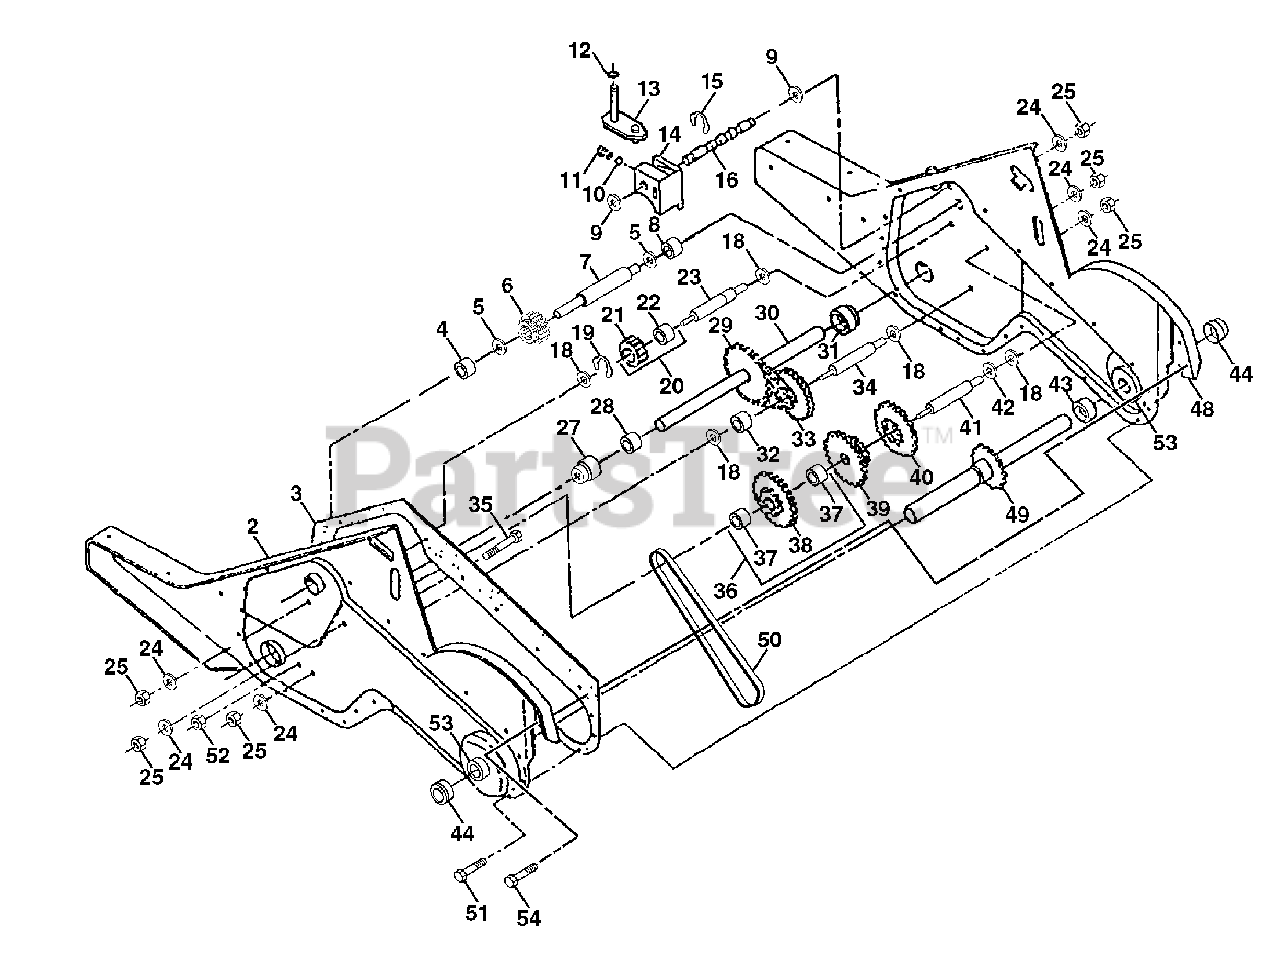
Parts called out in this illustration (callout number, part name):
1	Transmission Assembly
2	Gearcase, L.H. w/Bearing
3	Gasket, Gearcase
4	Bearing, Needle
5	Washer, Thrust 5/8 x 1.10 x 1/32
6	Pinion, Input
7	Shaft, Input
8	Bearing, Needle
9	Washer, Seal
10	Ball, Steel
11	Spring, Shift, Fork
13	Arm, Shift
14	Fork, Shift
15	Ring, Klip
16	Shaft, Shift
19	Ring, Klip
20	Gear, Assembly, Reverse Idler
21	Gear, Reverse Idler
22	Bearing, Needle
23	Shaft, Reverse Idler
24	Washer, Lock 7/16
25	Nut, Hex 7/16-20
27	Bearing, Shaft, Ground Drive L.H.
28	Spacer 0.765 x 1.125 x 1.23
29	Chain #35-50 Pitch
30	Ground Shaft Assembly
31	Bearing, Shaft, Ground Drive R.H.
32	Spacer 0.70 x 1.00 x 1.150
33	Sprocket and Gear Assembly
34	Shaft, Reduction (2nd)
35	Screw, Whiz, Lock 5/16-18 x 3-1/2
36	Sprocket Assembly w/Bearing
37	Bearing, Needle
38	Sprocket, Tine
39	Gear, Cluster, Red 1st & 2nd
40	Gear, Reverse
41	Shaft, Reduction (1st)
42	Washer, Thrust
43	Spacer 1.01 x 1.75 x 0.760
44	Seal Asm, Oil
48	Gearcase, R.H. w/Bearing
49	Shaft, Tine
50	Chain, Roller #50-50 Pitch
51	Screw 1/4-20 x 1/2
52	Nut, Hex 5/16-18
53	Kit, Bearing
54	Screw 1/4-20 x 3/4
54	Grease, Plastilube #1
